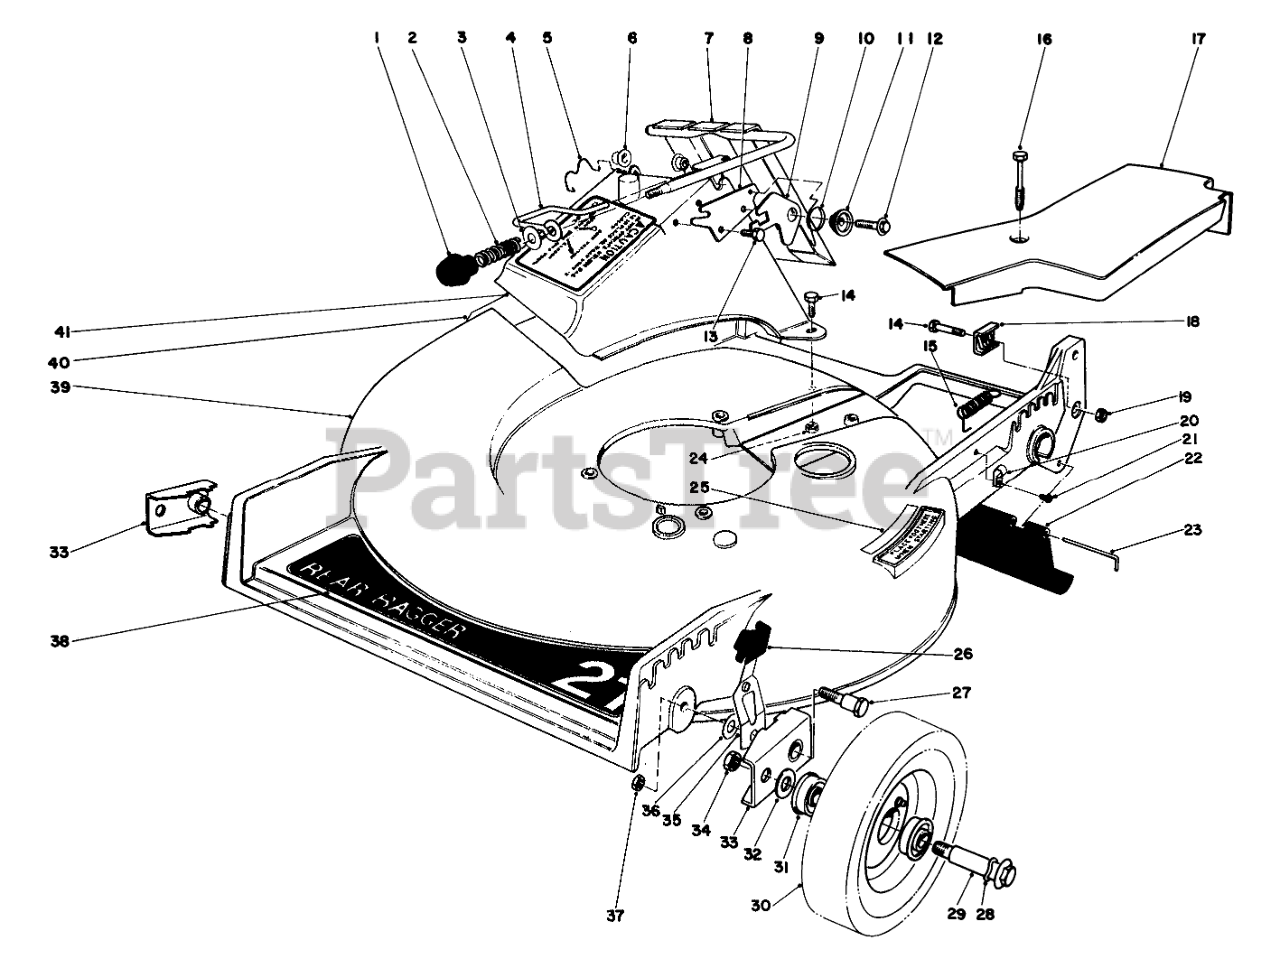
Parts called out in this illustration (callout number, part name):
2	COMPRESSION SPRING
3	WASHER-FLAT
4	DOOR LATCH
5	Door Retainer
6	BUSHING-NYLON
7	DOOR & HANDLE WA
8	DOOR LATCH PLATE
9	SAFETY LATCH
10	TORSION SPRING
11	DOOR SPACER
12	Screw
13	SCREW-HWH
14	SCREW-HH
15	IDLER SPRING
16	SCREW-HHFTF
17	Belt Cover
18	CLAMP-CABLE
19	NUT-JAM
20	CLAMP-CABLE
21	SCREW-HWH
22	SHIELD - TRAILING
23	Rod Shield
25	Decal-Place Foot Here
26	KNOB-ARM
27	PIVOT SCREW
28	SPRING WASHER
30	Wheel & Tire Assembly (Incl. Ref. #31)
31	BEARING-BALL
32	WASHER
33	Pivot Arm
34	Nut
35	Spring Arm
36	WASHER-PIVOT
37	Nut
38	Decal-Deck
39	Housing
40	Decal-Attention
41	DISCHARGE CHUTE B
